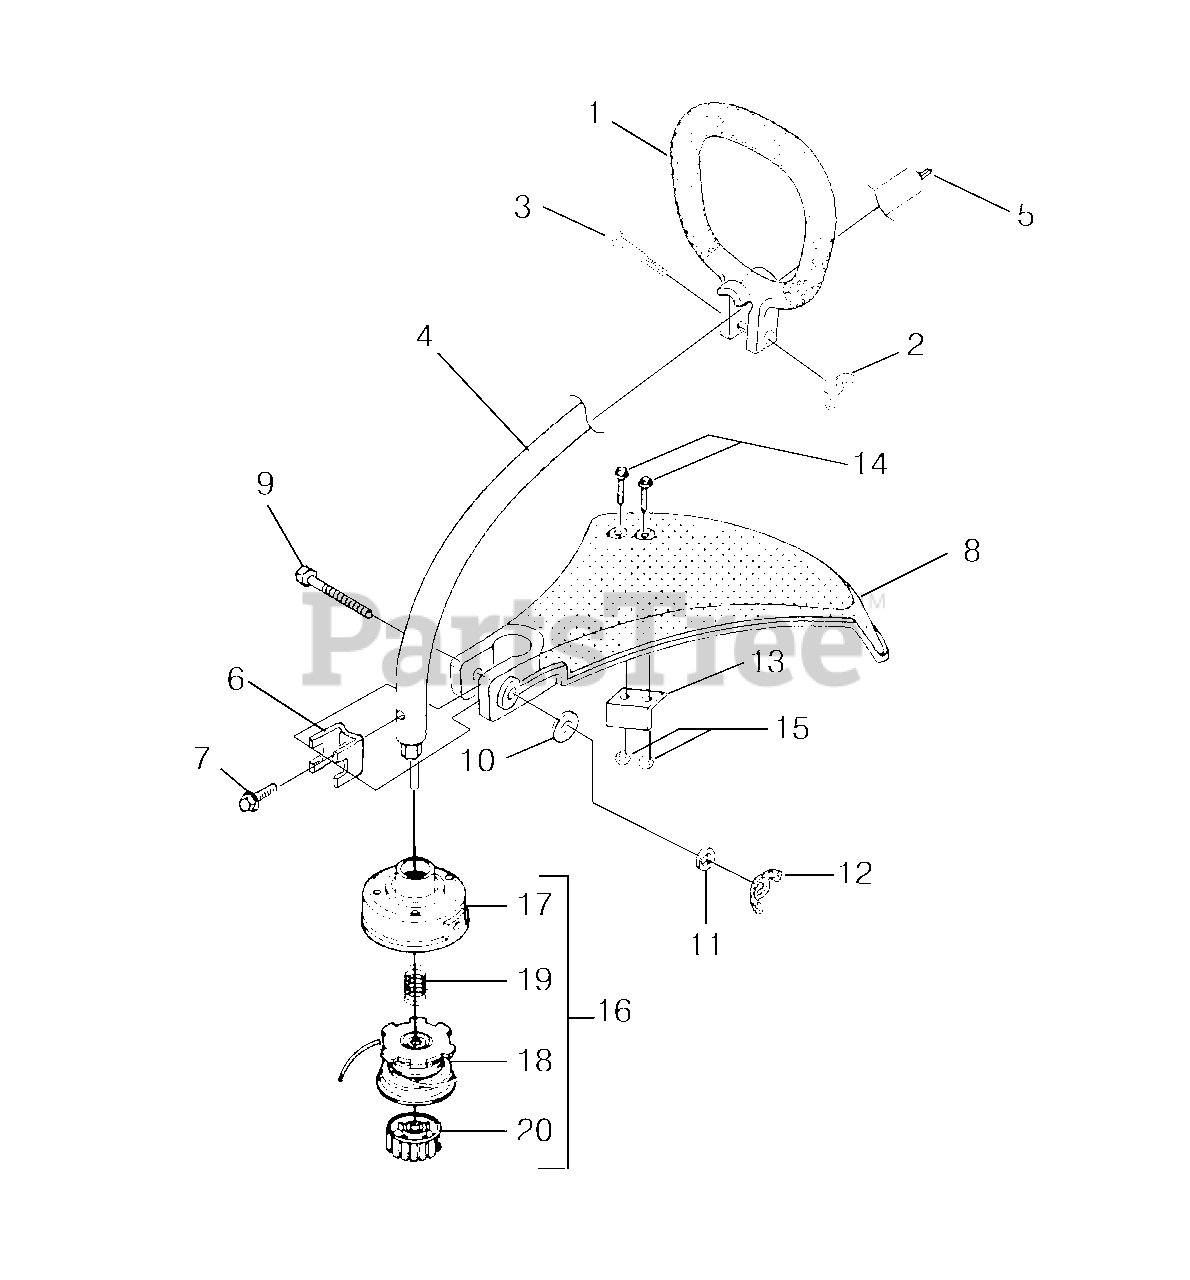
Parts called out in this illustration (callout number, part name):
1	HANDLE-Anti-Vibe
2	NUT-Wing, Washer Faced (1/4-20)
3	SCREW-Cap Hex Hd.
4	DRIVESHAFT HOUSING ASSY.
5	SHAFT-Flexible
6	CLAMP
7	SCREW-Sems Hex Hd. (#10-24 X 3/8")
8	DEFLECTOR & BLADE KIT (55 Deg.)
9	SCREW-Cap Hex Hd. (10-24 X 2")
10	WASHER-Flat (1/4")
11	WASHER-Lock (1/4")
12	NUT-Wing, Washer Faced (1/4-20)
13	BLADE-Cut-Off
14	SCREW-Mech. Hex Hd. (10-24 X 7/8")
15	NUT-Hex (10-24)
16	STRINGHEAD-Complete (.080")
17	HOUSING & EYELET (Dual Line)
18	SPOOL & STRING (.080")
19	SPRING-Compression
20	RETAINER-Spool (R.H. Thread, Black)
